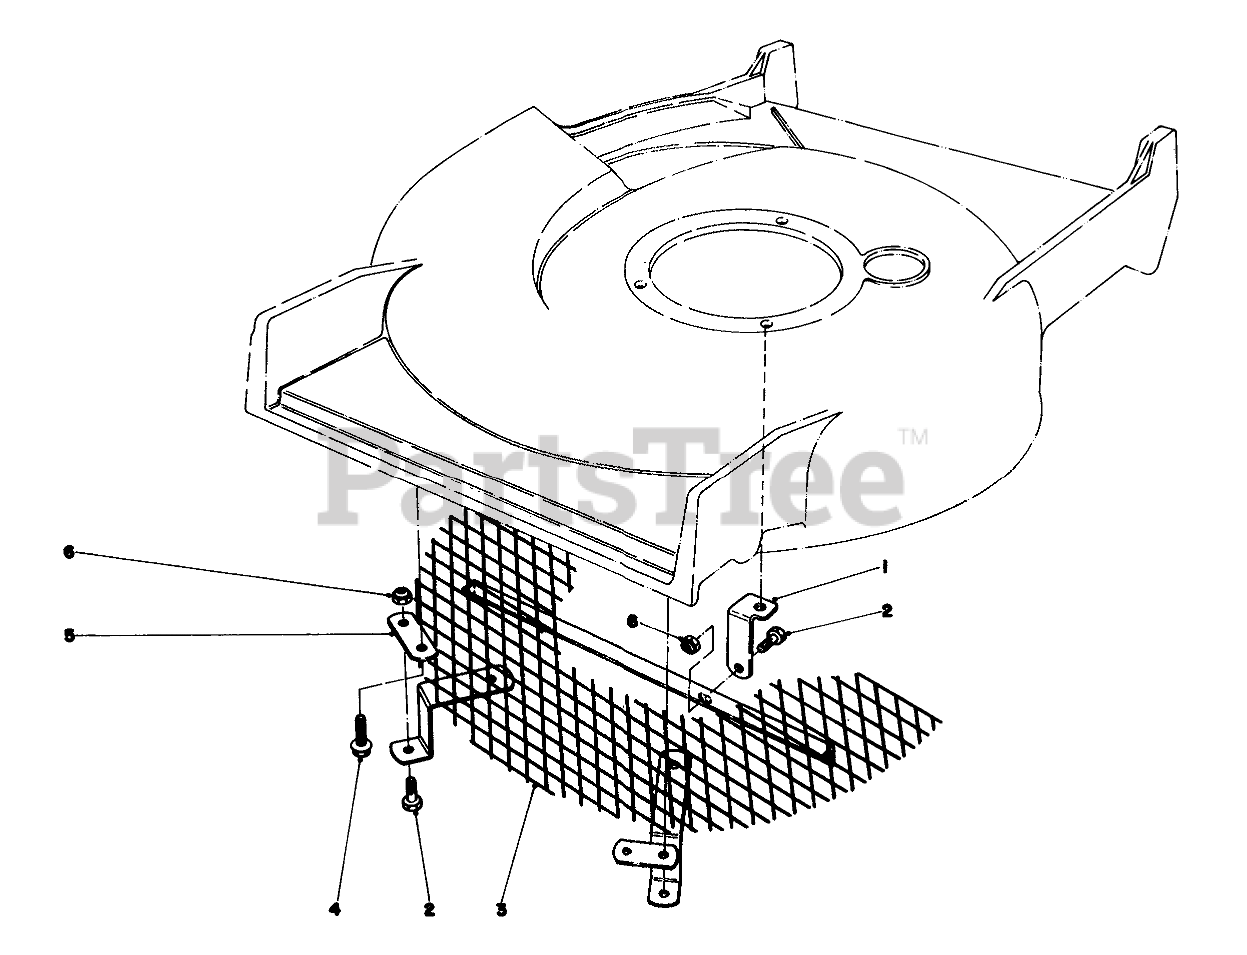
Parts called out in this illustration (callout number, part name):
1	Support Bracket
2	SCREW-HH
3	Screen
4	SCREW-HWHTF
5	ANCHOR
6	NUT-LOCK, NI
